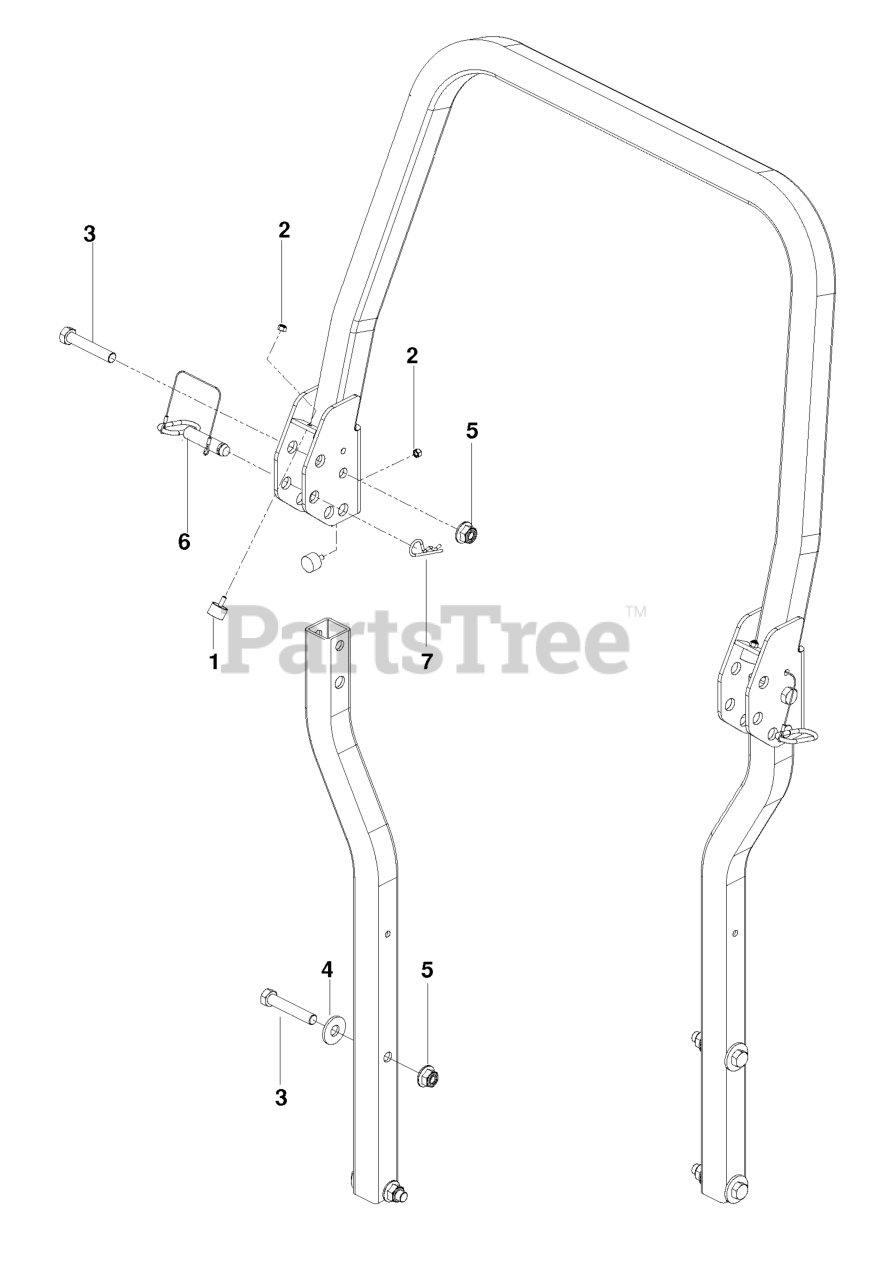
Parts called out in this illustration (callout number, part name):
1	BUMPER, MALE STUD, 1/4-20
2	NUT.1/4-20.HEX.NYLOC.ZD
3	5/8-11 X 3-1/2 HHB GRADE 5
4	WASHER, 5/8 FLAT
5	NUT 5/8-11 FLG NYLOC ZD
7	PIN HAIR .148 X 2-15/16 #210
